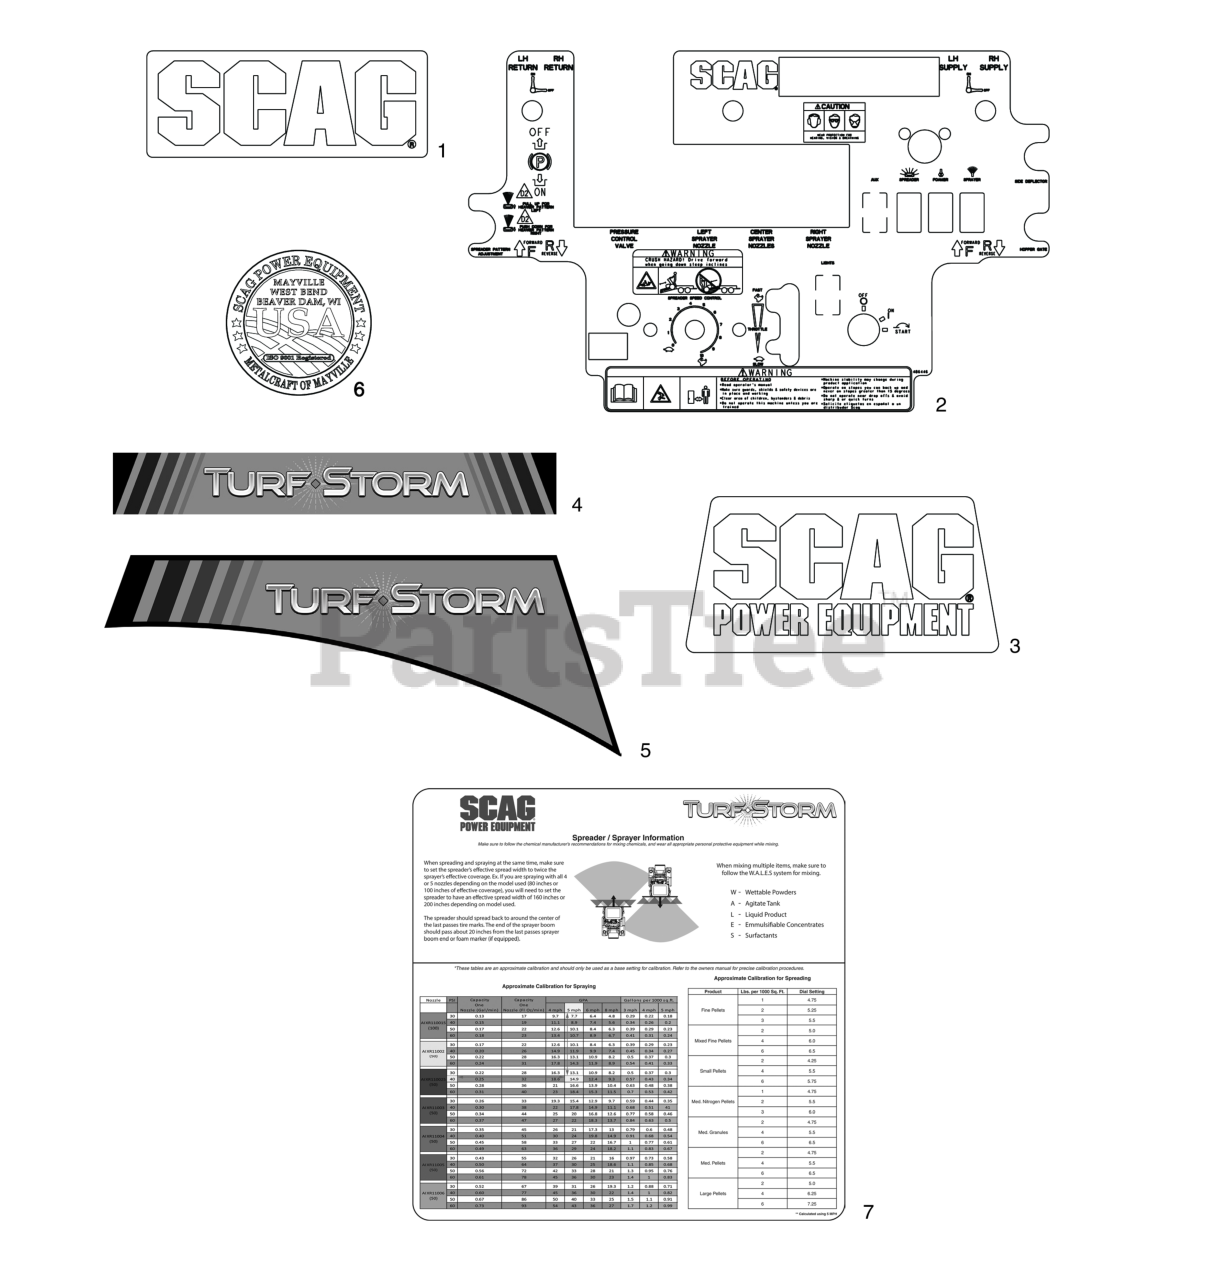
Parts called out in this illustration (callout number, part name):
1	Decal, Scag - Fuel Tank
2	Decal, Instrument Panel - Turf Storm
3	Decal, Scag Power Equipment (Fuel Tank)
4	Decal, Hopper Front - Turf Storm
5	Decal, LH Spray Tank - Turf Storm
6	Decal, Metalcraft - USA
7	Decal, Stray & Spread Instructions - Turf Storm
